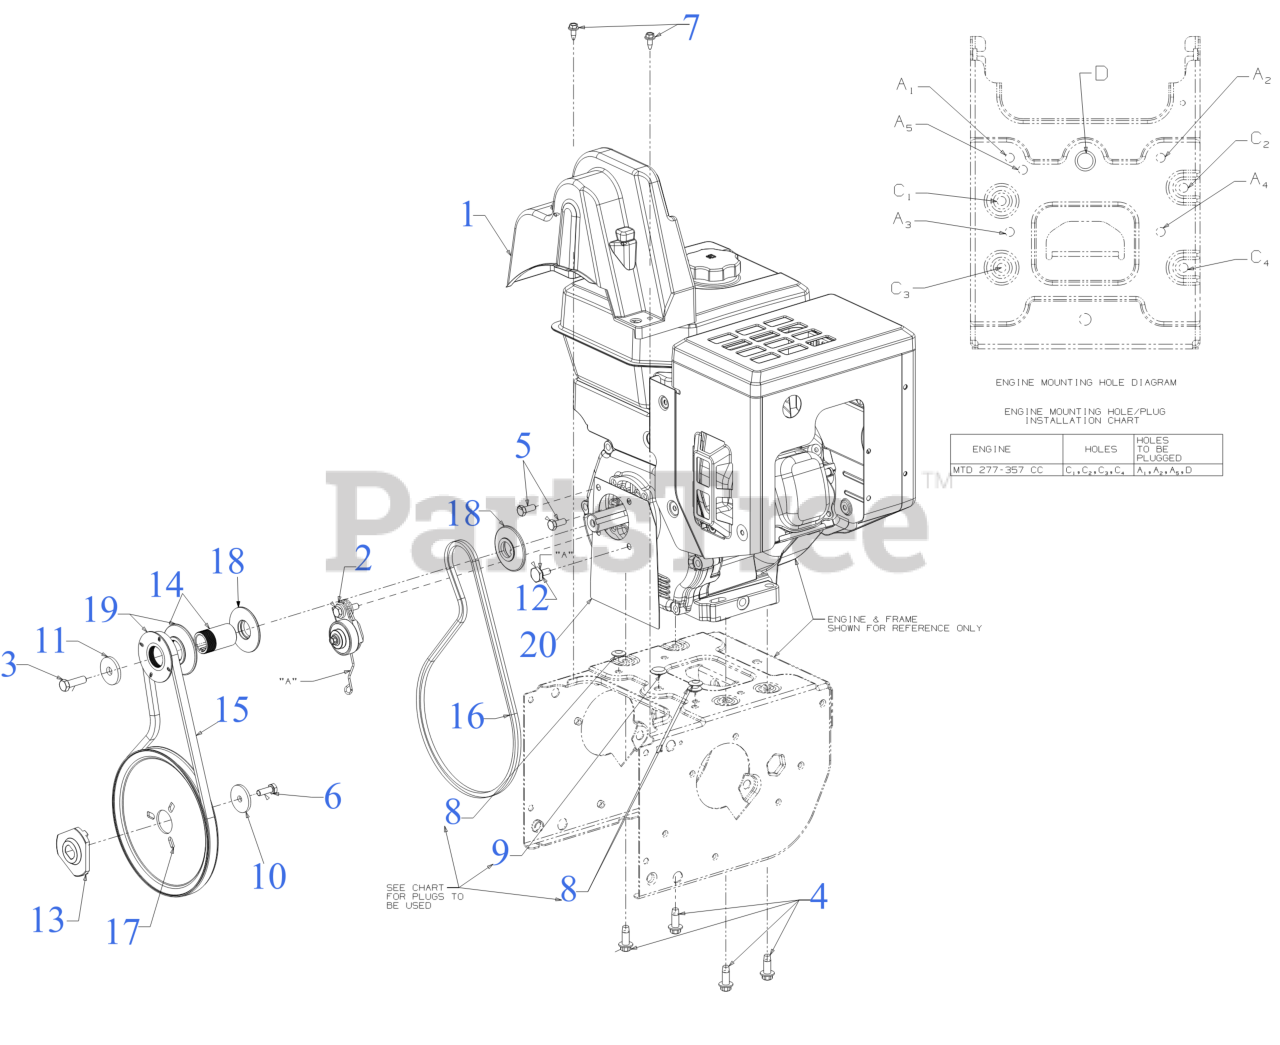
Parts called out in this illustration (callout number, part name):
1	BELT COVER SERVICE KIT (631-05323)
2	IDLER ASSEMBLY
3	SCREW 3/8-24X1.25
4	SCREW 3/8-16 x 1
5	SCREW 5/16-24 x .750 GR5
6	SCREW 5/16-24 x .875 GR5
7	SCREW 1/4-20X.625
8	PLUG-3/8 DIA ID x 3/32
9	PLUG-1/2 ID x 3/32
10	FLAT WASHER
11	FLAT WASHER .45 x 1.5 x .172 HT
12	SHOULDER SCREW
13	ADAPTER PULLEY .75 DIA W/DD
14	PULLEY SPACER
15	BELT-.500 x 37.00
15	Cub Cadet AUGER BELT
15	Troy-Bilt AUGER BELT (04195)
16	BELT-3L x 36.64 LG
16	Troy-Bilt 23" BLADE (BOWTIE)
17	AUGER PULLEY
18	HALF PULLEY 3/8-V x 2.2
19	HALF PULLEY A2.76 x 1.140 SPLINE
20	ENGINE PLATE (FRONT COVER)
